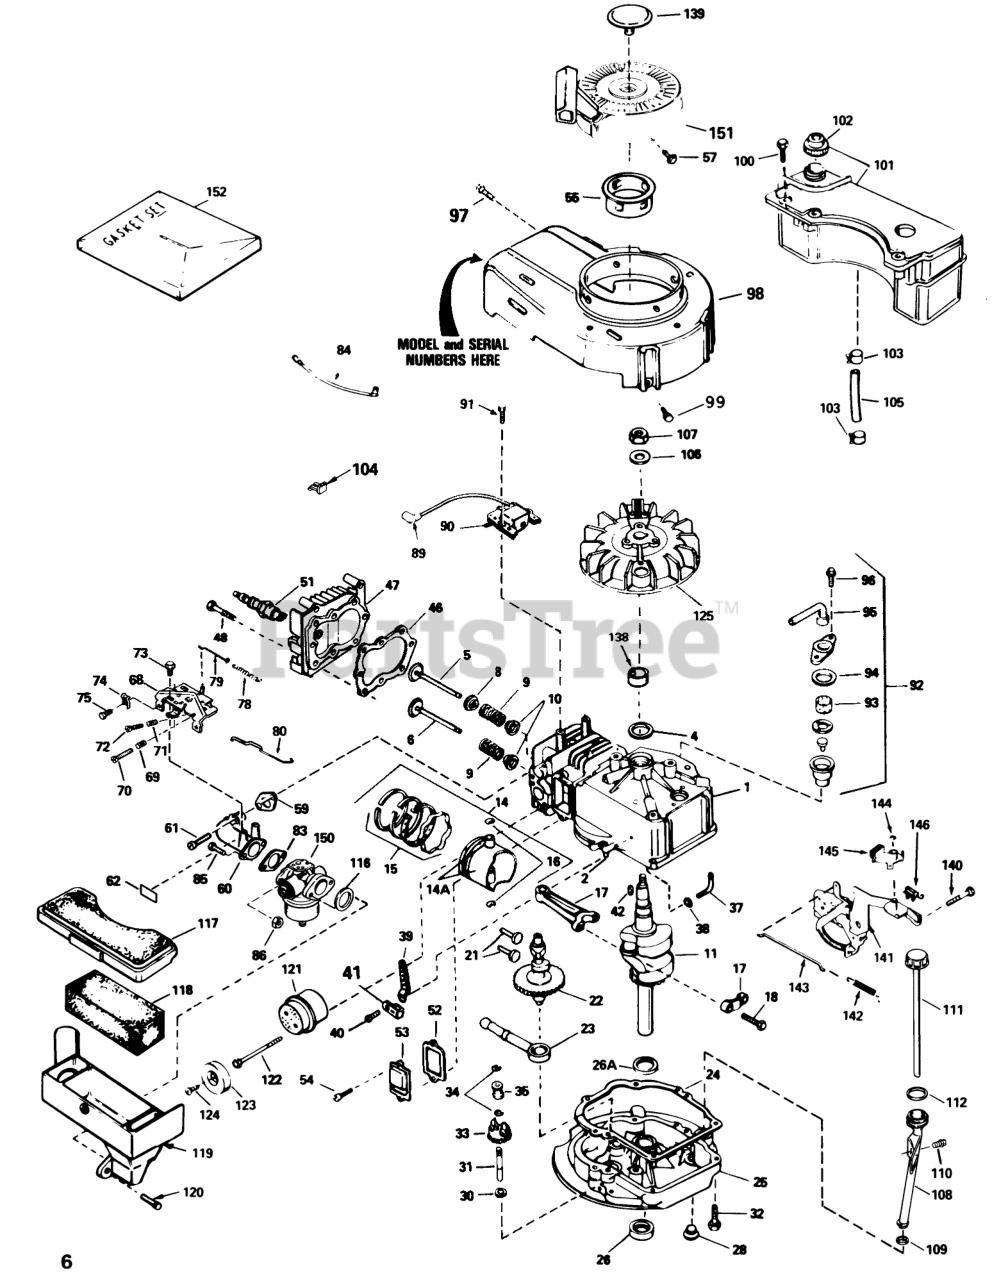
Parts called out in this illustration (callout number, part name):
1	Cylinder Assembly (Incl. Ref. #2 & 4)
2	Pin-Dowel
4	Seal-Oil
5	Valve-Intake (Std.) (Incl. Ref. #10)
5	Valve-Intake (1/32" oversize) (Incl. Ref. #10)
6	Valve-Exhaust (Std.) (Incl. Ref. #10)
6	Valve-Exhaust (1/32" oversize) (Incl. Ref. #10)
8	Seal Assy., Intake
9	Spring-Valve
10	Cap-Valve, Spring
11	Crankshaft
14	Piston-Pin & Ring Assy. (Std.) (Incl. Ref. #14A, 15 & 16)
14	Piston-Pin & Ring Assembly (.010 oversize) (Incl. Ref. #14A, 15 & 16)
14	Piston-Pin & Ring Assembly (.020 oversize) (Incl. Ref. #14A, 15 & 16)
14A	Piston & Pin Assembly (Std.) (Incl. Ref. #16)
14A	Piston & Pin Assembly (.010 oversize) (Incl. Ref. #16)
14A	Piston & Pin Assembly (.020 oversize) (Incl. Ref. #16)
15	Ring Set-Piston (Std.)
15	Ring Set, Piston(.0100versize)
15	Ring Set (.020" OS)
16	Ring-Retaining, Piston Pin
17	Rod Assembly-Connecting (Incl. Ref. #18)
18	Bolt-Rod, Connecting
21	Lifter-Valve
22	Camshaft(Mech.Comp. Release)
23	Oil Pump ASM
24	35261 Gasket-Mounting Flange
25	Flange Assembly-Mounting (Incl. Ref. #26, 28 & 31)
26	Seal-Oil
26A	Washer-Thrust
28	Plug Oil Drain
30	Washer-Flat
31	Shaft-Governor
32	Screw (1/4-20 x 1-1/4)
33	Gear Assembly-Governor (Incl. Ref. #30)
34	Ring-Retaining
35	Spool-Governor
37	Rod-Governor (Incl. Ref. #38)
38	Washer-Flat
39	Governor Lever
40	Screw
41	Clamp-Lever, Governor
42	Key-Flywheel
46	33015 Gasket-Cylinder Head
47	Head-Cylinder
48	Screw (5/16-18x1-1/2)
51	Spark Plug-Resistor (R J19 L M)
52	27234 Gasket-Breather
53	Cover-Valve
55	Hub-Starter
57	Screw, Hex Hd.
59	34690 Gasket-Intake Pipe
60	Pipe-Intake (Incl. Ref. #59)
61	Screw (1/4-20 x 1)
62	Decal-Primer
68	Control Assy.-Remote Speed (Incl. Ref. #69 thru 72)
69	61709/GIL1515A/95-5
70	Screw
71	Spring-Compression
72	Screw
73	Screw (10-24 x 9/16)
74	Conduit
75	Screw (10-32 x 3/8)
78	Spring Governor
79	2035A67 ADD.ASSEMBL
80	Link-Throttle
84	Ground Wire
85	Screw (1/4-28 x 7/8)
86	Nut and Lock Washer (1/4-28)
89	Cover-Spark Plug
90	Solid State
91	Screw
92	Breather Assembly (Incl. Ref. #93 thru 96)
93	Element-Breather
94	Gasket-Breather
95	Tube, Breaker
96	Screw (10-24 x 9/16)
97	Screw (10-24 x 9/16)
98	Housing-Blower
99	Screw (1/4-20 x 1/2)
100	Screw (10-32 x 35/64)
101	Tank Assembly-Fuel (Incl. Ref. #102)
102	Cap-Fuel
103	Clamp-Line, Fuel
104	Clip-Wire
105	Line-Fuel
106	Washer-Belleville
107	Nut-Flywheel
108	Oil Fill Tube
110	Screw (10-32 x 1/2)
111	Dipstick
116	Gasket-Cleaner, Air
117	Cover-Air Cleaner
118	Filter-Air Cleaner
119	Body Air cleaner
121	Muffler (Incl. Ref. #122)
123	Cover-Muffler
124	Screw (8-32 x 3/8)
125	Flywheel
139	Plug Starter
140	Screw (1/4-20 x 3/8)
141	Bracket-S.E. Brake
142	Spring-Extension
143	Link-Control
144	Ring-Retaining
145	Lever-Brake
146	Terminal
150	Carburetor (Inc. Ref. #83)
151	Starter-Rewind
152	Gasket Set (Incl. Items Marked )
